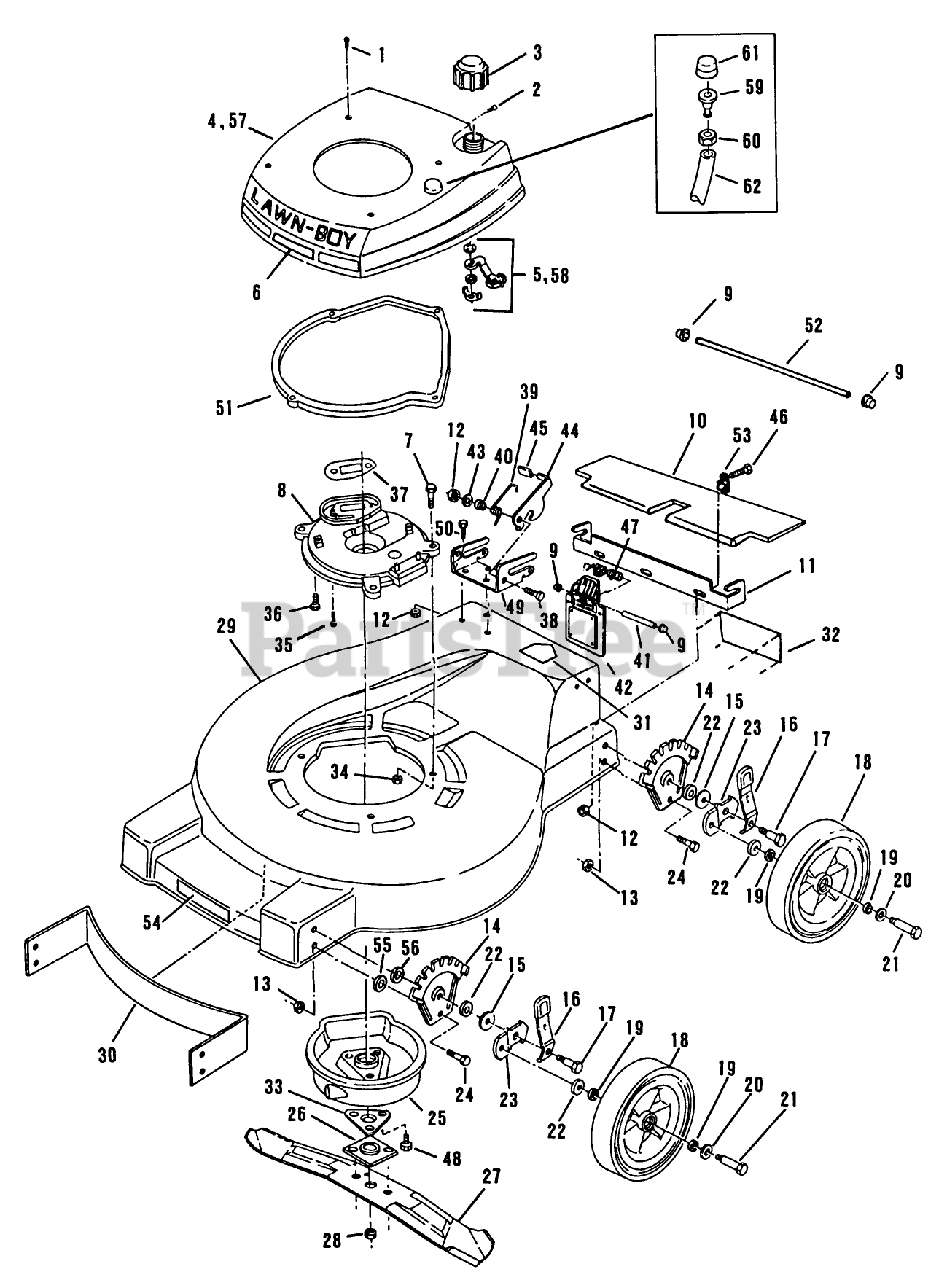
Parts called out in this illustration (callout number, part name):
1	SCREW LAWRENCE
2	SCREW S
3	FUEL CAP & INSERT
7	SCREW-HH
8	PLATE,MUFFLER F
10	T/SHIELD SM&P
12	LOCKNUT E
13	LOCKNUT
15	WASHER
16	KNOB&SPRING FORMCO
17	BOLT
19	WASHER
20	SPACER
21	BOLT WHEEL
22	WASHER WROUGHT
26	PLATE AND COLLAR ASM
28	NUT-BLADE
33	SUPPORT F
34	NUT-LOCK F
35	SCREW V
39	SPRING
41	ROD ROCK/HDWE
45	KNOB (S&R)
47	SPRING ASOC
48	SCREW
55	WASHER
56	WASHER
60	LOCKNUT S
61	P-BULB LAV-RUB
62	TUBING-PRIMER POLY
